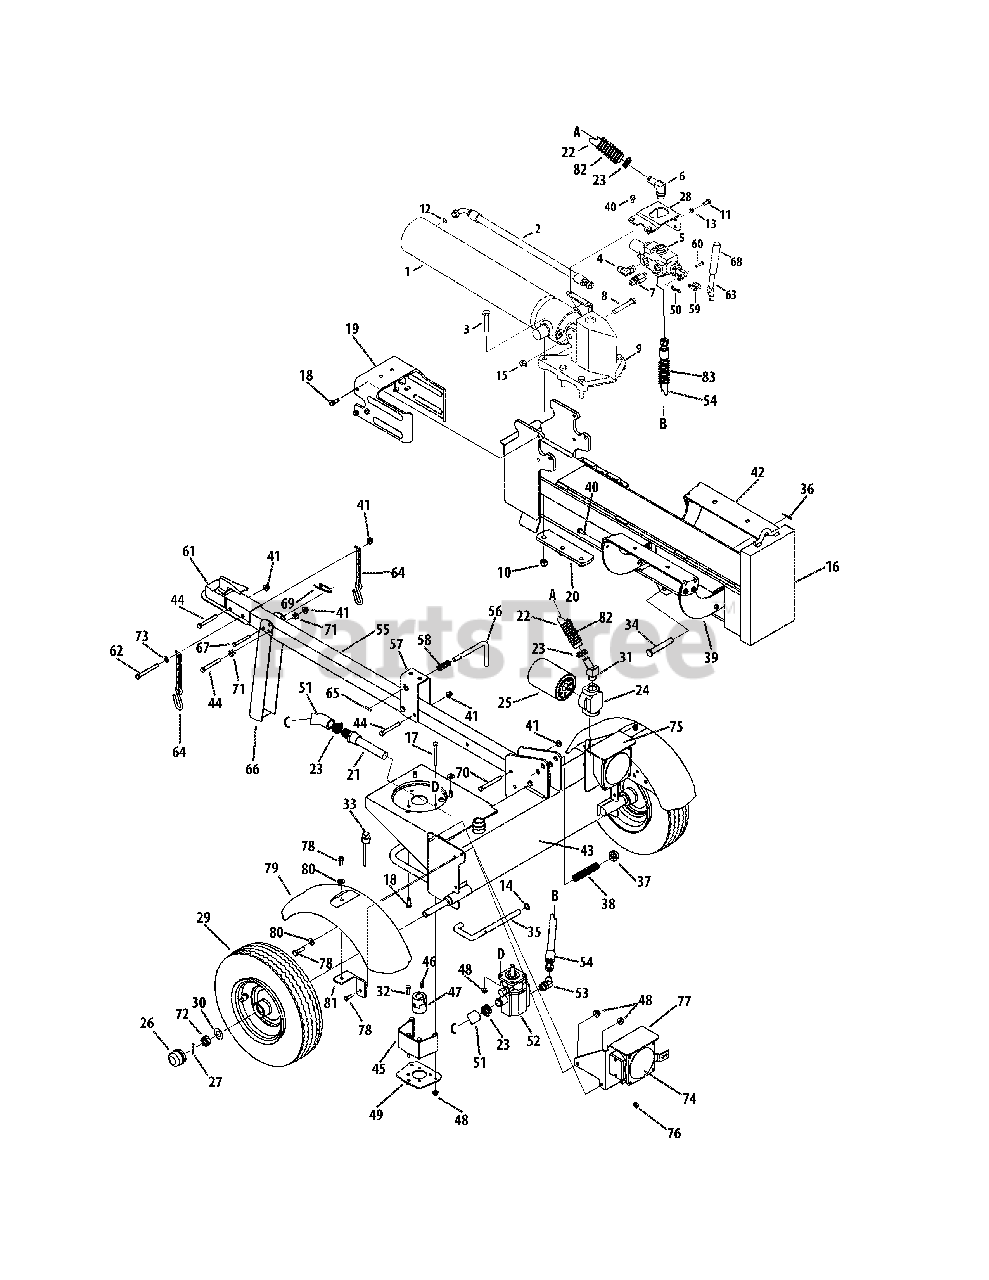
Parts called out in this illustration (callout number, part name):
1	Hydraulic Cylinder
2	Hydraulic Tube
3	Hex Cap Screw, 1/2-20 x 2.75
4	90 Degree Solid Adapter
5	Control Valve
6	Return Elbow
7	Nipple Pipe, 1/2-14
8	Hex Cap Screw, 1/2-13 x 3.25
9	Wedge Assembly
10	Hex Lock Nut, 1/2-20
11	Hex Cap Screw, 3/8-16 x .75
12	O-Ring, .419 ID x .070 Dia.
13	Lock Washer, 3/8
14	Flat Washer, .635 x.93 x.06
15	Hex Lock Nut, 1/2-13
16	Beam Assembly
17	Hex Screw, 5/16-18 x 3.25
18	Self Tapping Screw, 3/8-16 x 1.0
19	Dislodger Bracket
20	Back Plate
21	Inlet Filter
22	Return Hose, 3/4 x 44
23	Hose Clamp, 5/8
24	Filter Housing
25	Oil Filter
26	Hub Cap
27	Cotter Pin
28	Outer Valve Bracket
29	Complete Wheel Assembly
29	Dust Seal
29	Roller Bearing
30	Flat Washer, .760 x.500
31	Hydraulic Fitting, 1 1/16 Orb x .75
32	Hex Screw, 5/16-18 x 1.00
33	Vented Dipstick
34	Clevis Pin
35	Lock Rod
36	Cotter Pin
37	Push Cap
38	Compression Spring
39	Log Tray Bracket
40	Hex Washer Screw, 5/16-18 x .750
41	Flange Lock Nut, 3/8-16
43	Frame Assembly
44	Hex Bolt, 3/8-16 x 3
45	Coupling Shield
46	Square Key, 3/16" x .75
47	Log Splitter Coupling
47	Coupling, .500
47	Coupling, .875
47	Spider Bushing
47	Set Screws
48	Flange Lock Nut, 5/16-18
49	Rear Coupling Support Bracket
50	Cotter Pin, Bow Tie
51	Hose
52	Gear Pump
53	45 Degree Elbow Fitting
54	High Pressure Hydraulic Hose
55	Tongue Assembly
56	Latch Rod
58	Compression Spring
59	Valve Handle Link
60	Clevis Pin
61	Hitch Coupling Assembly
62	Hex Cap Screw, 3/8-16 x 3.50
63	Hydraulic Valve Control
65	Spiral Pin
66	Jack Stand
67	Clevis Pin
69	Spring Pin
70	Hex Cap Screw, 3/8-16 x 3.50
71	Plastic Bushing, .380 ID
72	Slotted Nut, 3/4-16
73	Flat Washer, .375 x.738 x.063
74	Light Assembly Kit
75	LH Light Bracket
76	Jam Nut, 3/8-16
77	RH Light Bracket
78	Self-Tapping Screw, 5/16-18 x 1.00
79	Fender
80	Flat Washer
81	Fender Mounting Bracket
82	Hose Guard, 48"
83	Hose Guard, 44"
